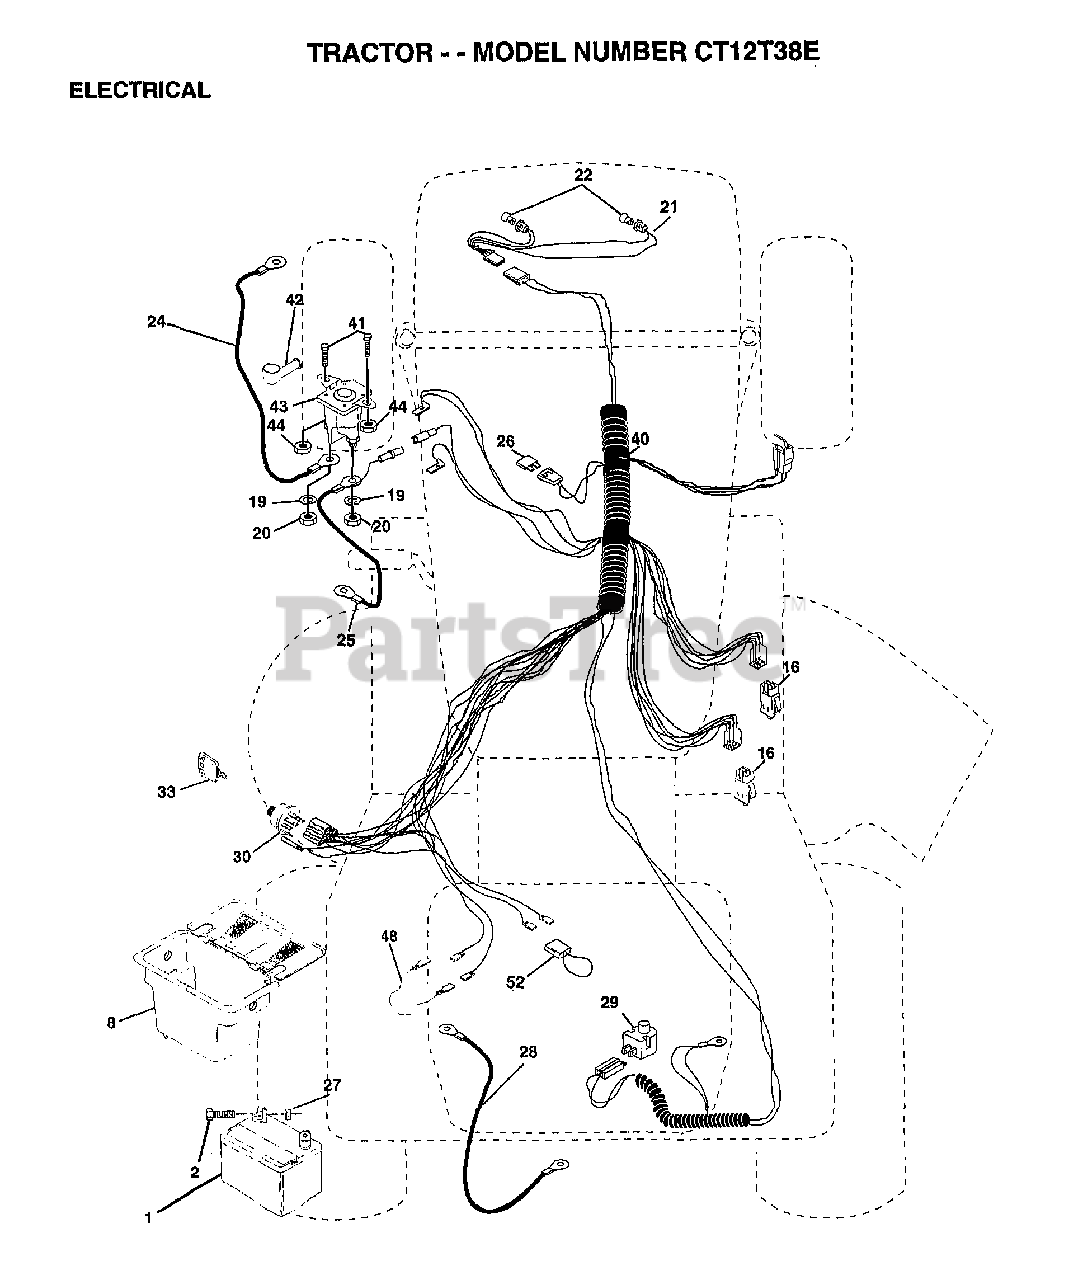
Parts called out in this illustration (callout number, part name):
2	BOLT LT
8	"CASE,BATTERY.MECH"
16	SWITCH INTERLOCK
20	NUT
21	HARNESS.ASM.LIGHT W/4152J
22	HEADLAMP BULB
24	CABLE ASM.
25	CABLE.BTRY.6GA.RD
26	FUSE.15 AMP
27	NUT
28	CABLE T
29	SWITCH SEAT
30	SWITCH.IGN.
33	KEY MLD GEN DELTA
40	IGNITION.HARNESS/MECH
41	BOLT HXHD FIN
44	NUT HXKEP 1/4X20
48	ADAPTER AMMETER
52	PROTECTION LOOP
